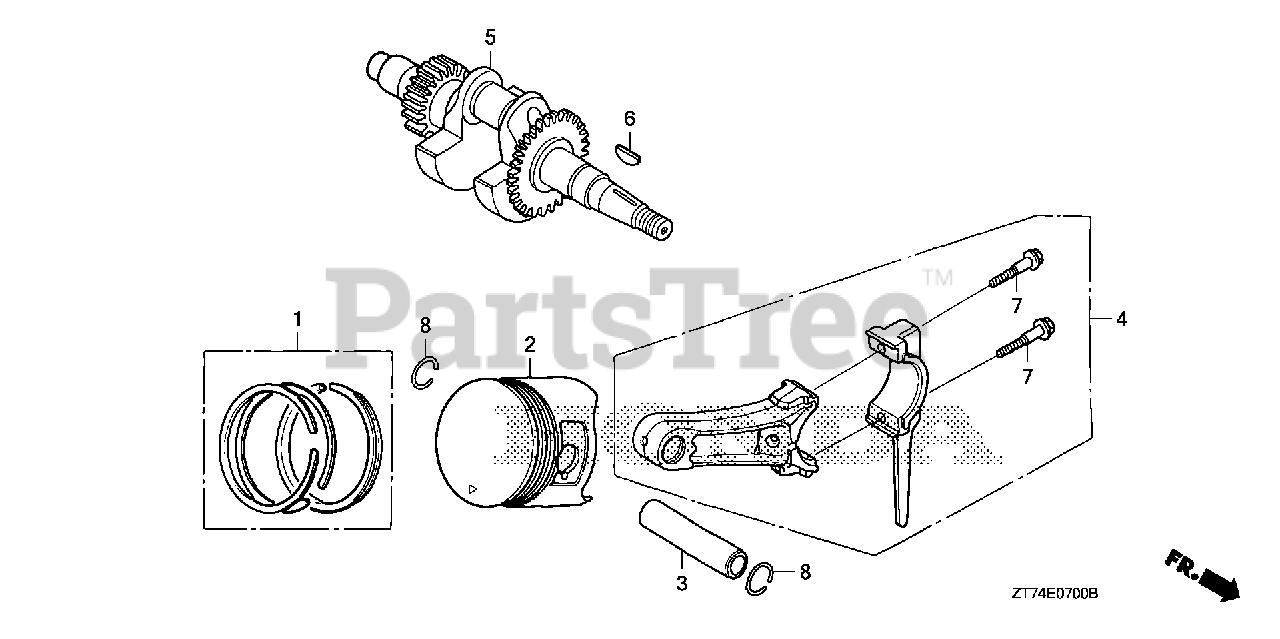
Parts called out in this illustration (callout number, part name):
1	RING SET, PISTON (STD) (TEIKOKU)
1	RING SET, PISTON (STD.) (NIPPON)
1	RING SET, PISTON (STD) (TPR)
1	RING SET, PISTON (0.25) (TEIKOKU)
1	RING SET, PISTON (0.25) (NIPPON)
1	RING SET, PISTON (0.25) (TPR)
1	RING SET, PISTON (0.50) (TEIKOKU)
1	RING SET, PISTON (0.50) (NIPPON)
1	RING SET, PISTON (0.50) (TPR)
1	RING SET, PISTON (0.75) (TEIKOKU)
1	RING SET, PISTON (0.75) (NIPPON)
1	RING SET, PISTON (0.75) (TPR)
2	PISTON (STD)
2	PISTON (0.25)
2	PISTON (0.50)
2	PISTON (0.75)
3	PIN, PISTON
4	ROD ASSY., CONNECTING (STD)
4	ROD ASSY., CONNECTING (TH)
5	CRANKSHAFT
6	KEY, SPECIAL WOODRUFF (25X18)
7	BOLT, CONNECTING ROD
8	CLIP, PISTON PIN (18MM)
